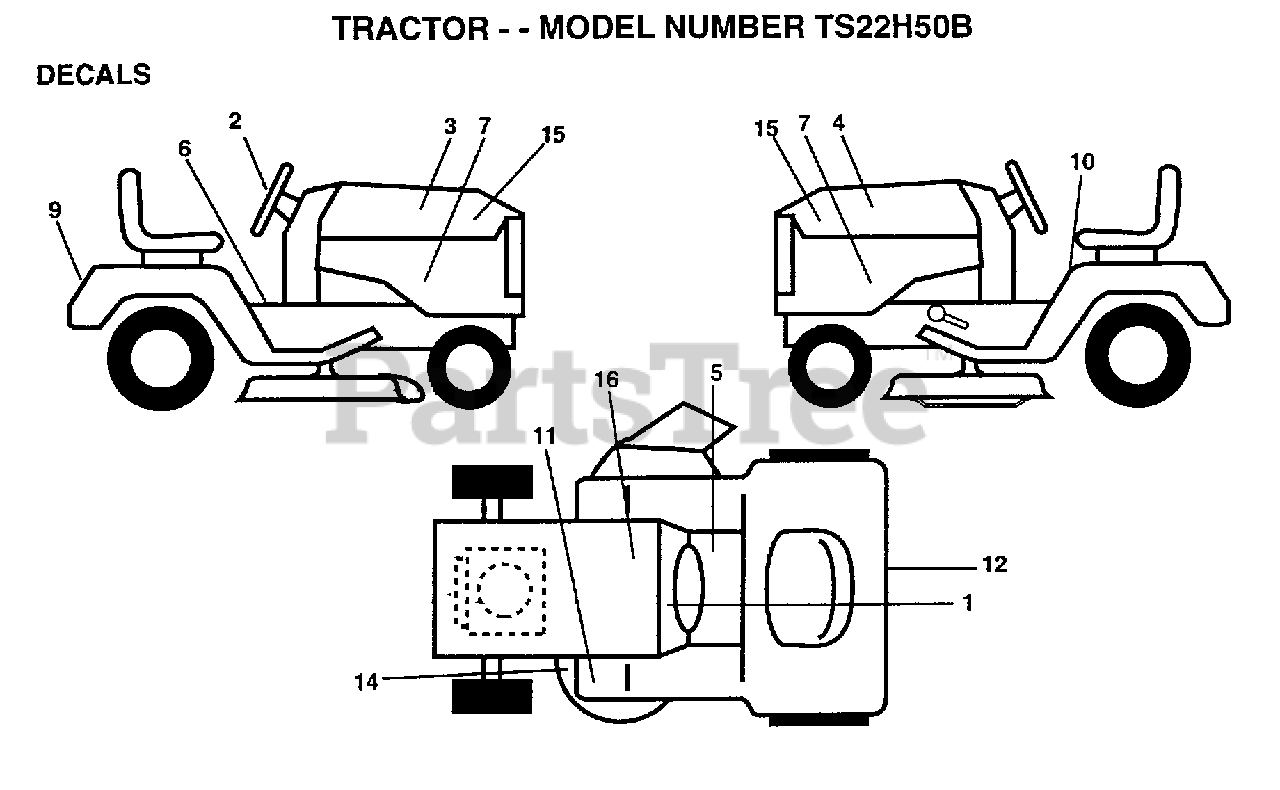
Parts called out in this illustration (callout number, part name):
1	DECAL, operating Instruction
2	DECAL.INS.STG.WHL
3	DECAL-HOOD,RH
4	DECAL-HOOD,LH
5	DECAL BRAK PARK
6	DECAL SADLE HYDRO
7	DECAL.PANEL,SIDE
9	DECAL.FEND.YT/GT
10	DECAL
12	DECAL D-BAR CNTRL
14	DECAL.V.BELT.44"
15	NAMEPLATE.HUSK.LG
16	DECAL.BTRY.DANGER
